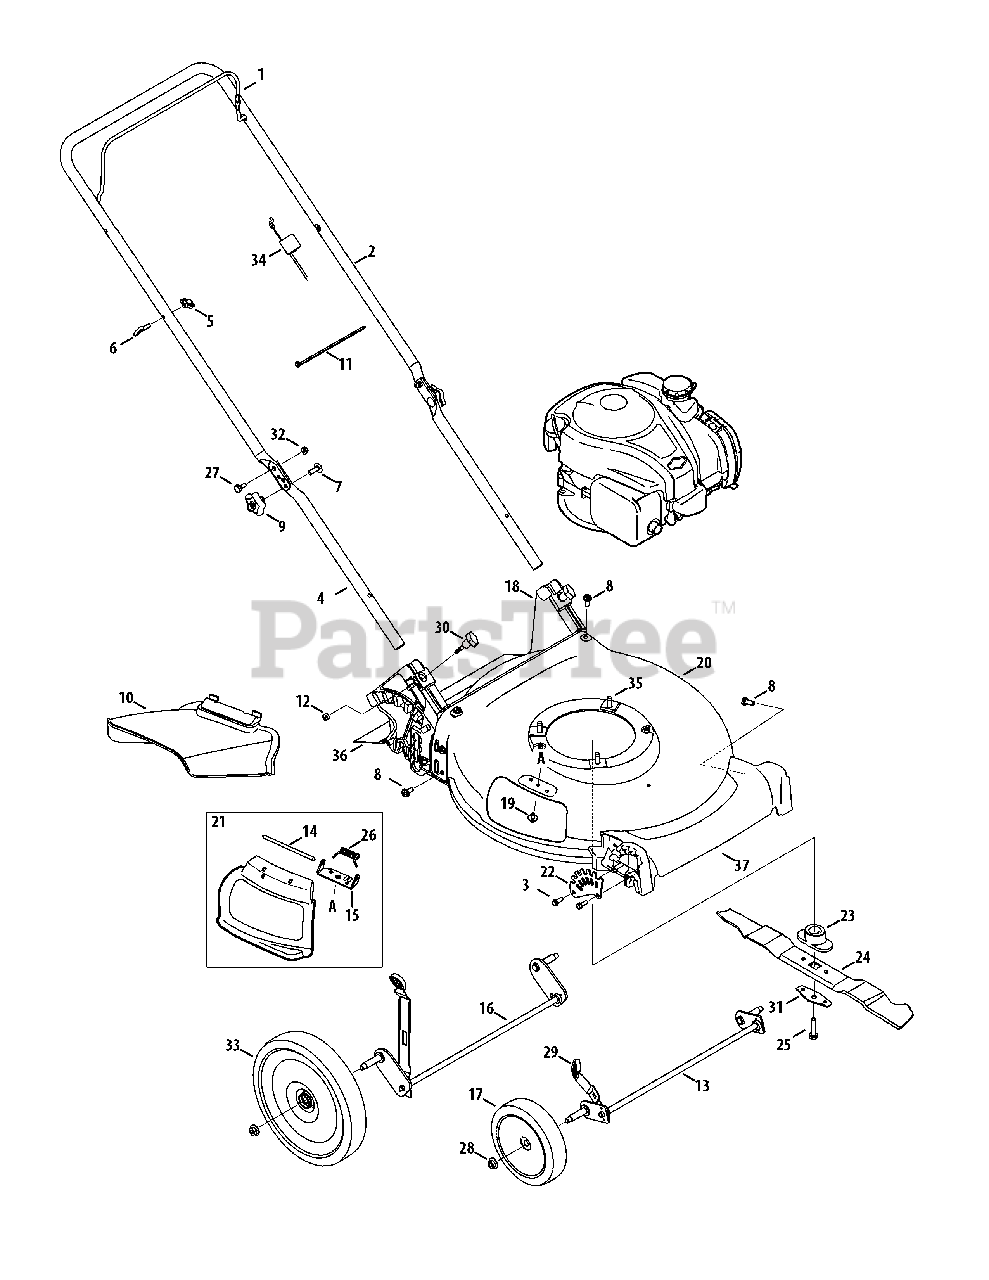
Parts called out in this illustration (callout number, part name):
1	Blade Control
2	Upper Handle
3	Screw, 1/4-15 x .750
4	Lower Handle
5	Wing Nut
6	Rope Guide
7	Carriage Screw ,5/16-18
8	Screw, 5/16-14 x .750
9	Hand Knob
10	Side Chute
11	Cable Tie
12	Nut, Sq., 1/4-20
13	Front Axle Assembly
14	Hinge Pin
15	Chute Deflector Bracket
16	Rear Axle Assembly
17	Wheel, 7 x 1.8
18	Rear Baffle
19	Screw, 1/4-20 x .500
20	Deck - 21"
21	Hinged Mulch Plug Assembly
22	Front Height Adjuster Plate
23	Blade Adapter
24	Mulching Blade
25	Screw , 3/8-24 x 1.50
26	Torsion Spring
27	Sldr. Screw, .375 x .126 x 1/4-20
28	Flange Lock Nut, 3/8-16
29	Adjustment Lever Knob
30	Wing Nut
31	Blade Bell Support
32	Nut, Flange Lock, 1/4-20
33	Wheel, 11 x 1.75
34	Control Cable
35	TT Screw, 3/8-16 x 1.0
36	Trail shield
37	Front Cover
